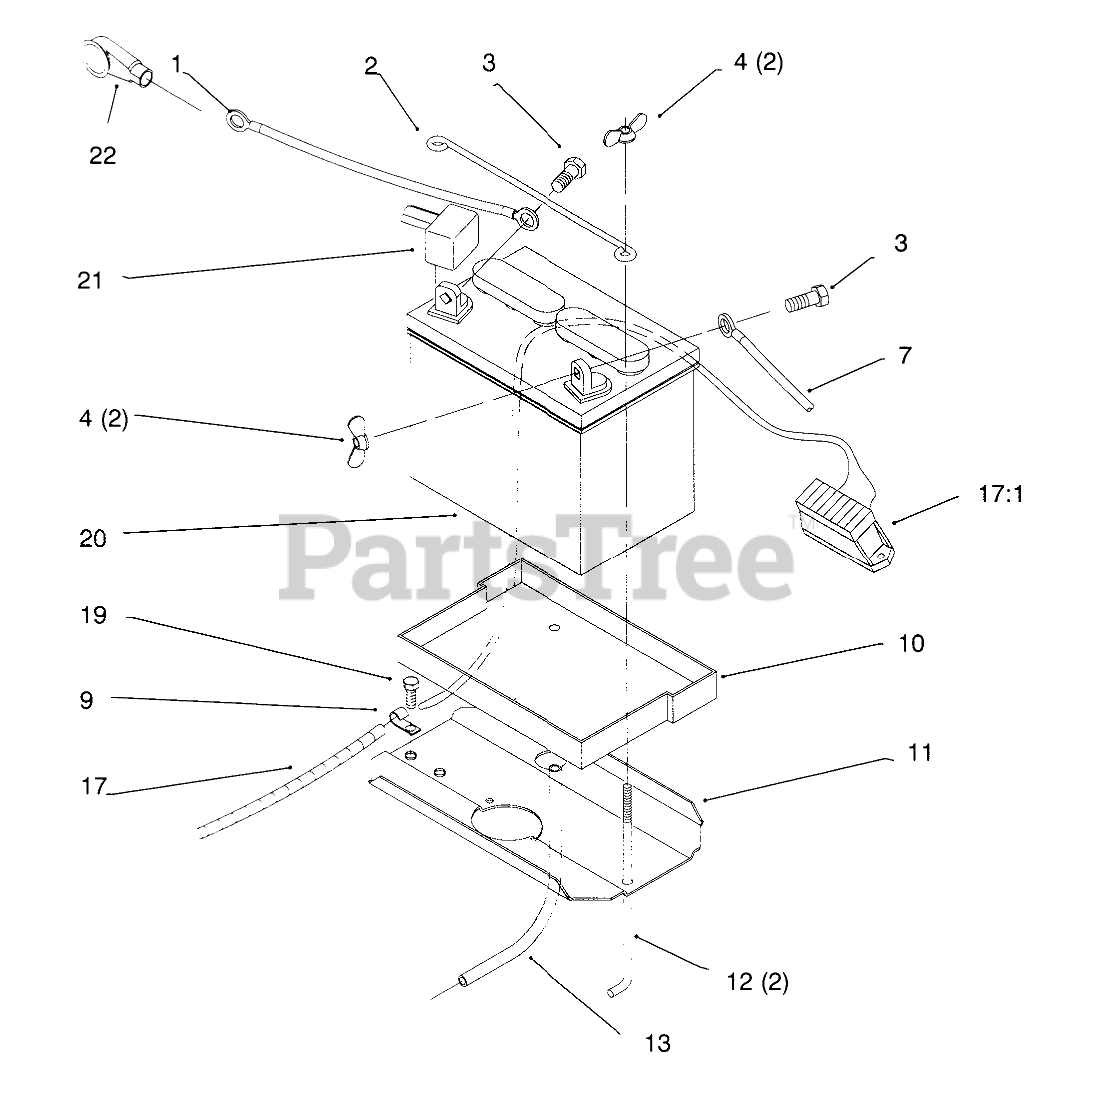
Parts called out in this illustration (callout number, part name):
1	WIRE-21 INCH
2	ROD-BATTERY HOLD DWN
3	SCREW-HH
4	NUT-WING
7	CABLE
9	CLIP
10	TRAY-BATTERY
11	PLATE-BATTERY
13	TUBE-21" BATTERY DRAIN
17	WIRE HARNESS
19	SCREW-HWHTF
20	Battery
21	Boot
22	BOOT-INSULATOR, TERMINAL
